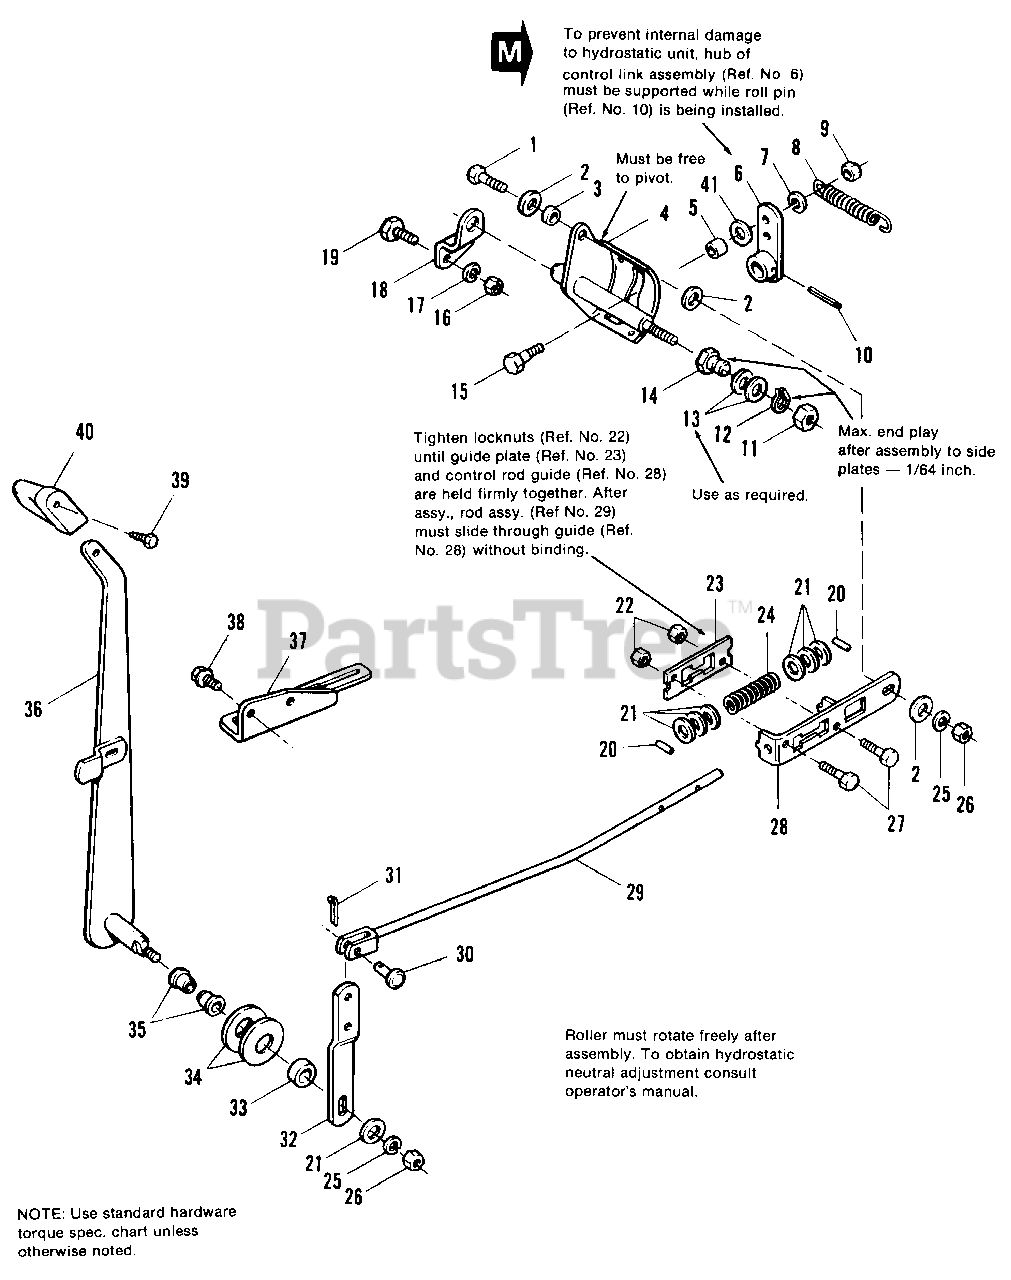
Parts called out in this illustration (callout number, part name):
1	CAPSCREW, Hex Hd., 3/8-16 x 1
2	WASHER, Plain, 5/16
4	SHAFT ASSY.
5	ROLLER, Cam
6	LINK ASSY., Control
7	LOCKWASHER, 1/4
9	NUT, Hex, Full, 1/4-20
10	PIN, Roll, 1/4 x 1-1/4
11	LOCKNUT, Hex, Jam, 1/2-13
12	RING, Retaining
13	SHIM (as required)
14	NUT, Adjusting
15	BOLT, Shoulder
16	NUT, Hex, Full, 5/16-18
17	LOCKWASHER, 5/16
18	BRACKET, Pivot
19	SCREW, Special
20	PIN, Roll, 1/8 x 5/8
21	WASHER, Plain, 3/8
22	LOCKNUT, Hex, 1/4-20
23	PLATE, Guide
25	LOCKWASHER, 3/8
26	NUT, Hex, Full, 3/8-16
27	CAPSCREW, Hex Hd., 1/4-20 x 1-1/4
28	GUIDE, Control Rod
29	ROD ASSY., Control
31	PIN, Cotter, 3/32 x 3/4
36	LEVER ASSY., Control
37	QUADRANT
38	SCREW, Hex, Flange, Whiz, 5/16-18 x 1/2
39	SCREW, Self Tapping, 1/4-20 x 1-1/4
41	WASHER, Plain, 1/4
